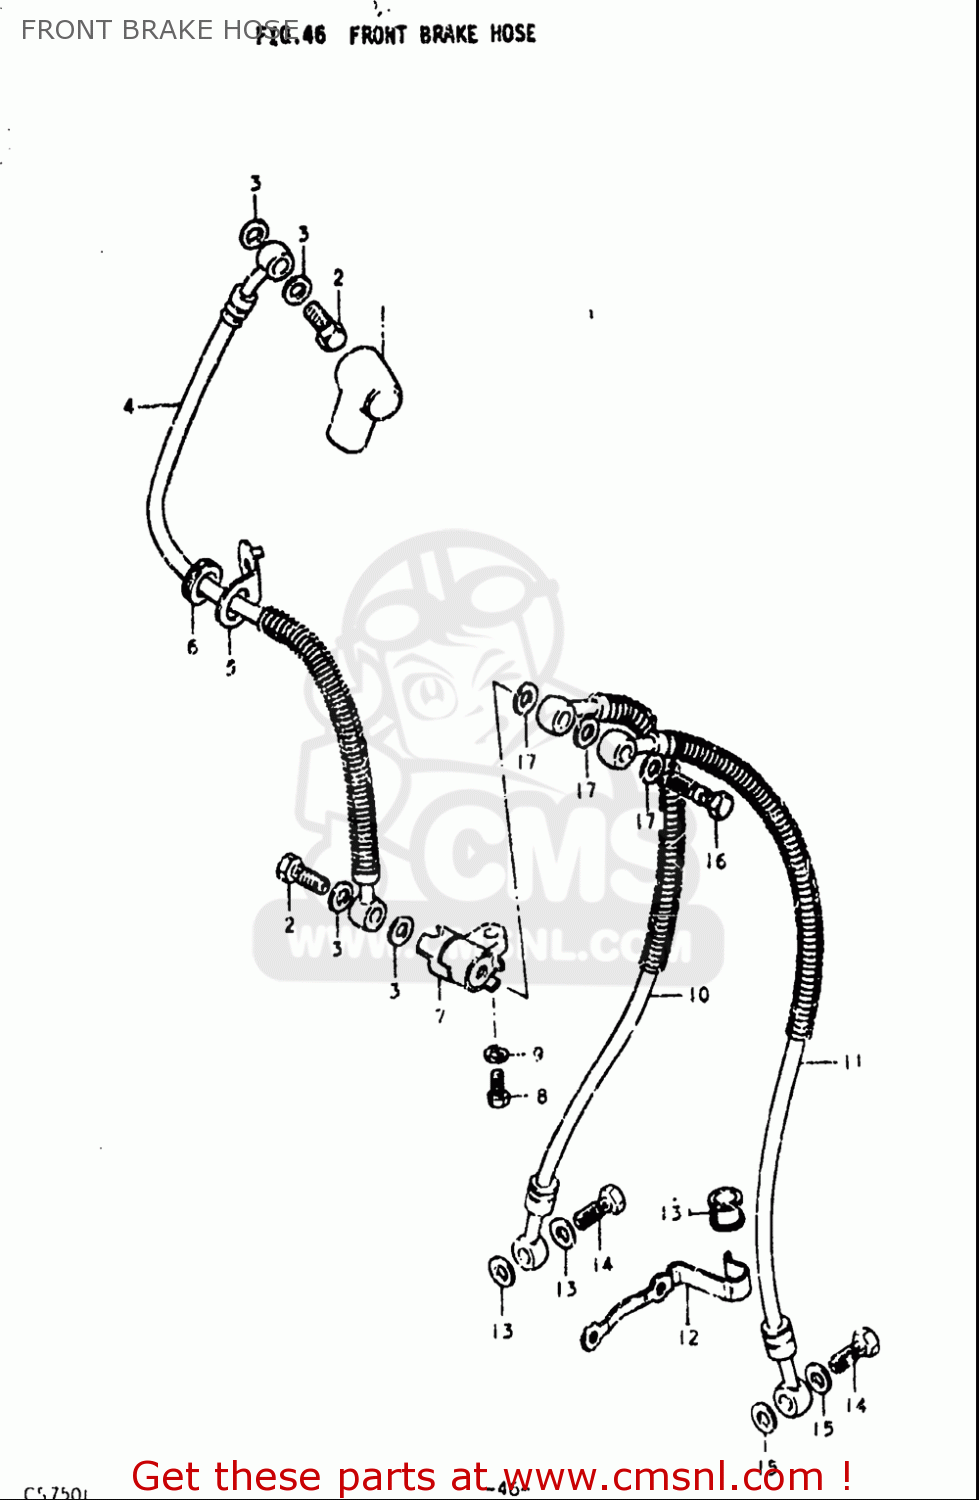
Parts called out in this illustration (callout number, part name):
1	BOOT,MASTER CYLINDER
2	BOLT UNION
3	WASHER(10X15X1.5)
4	HOSE,FRONT BRAKE NO.1
5	GUIDE,BRAKE HOSE
6	GROMMET
7	JOINT,BRAKE HOSE
8	BOLT
9	WASHER,LOCK
10	HOSE,FR BRAKE NO.2,L
12	GUIDE,BRAKE HOSE NO.2
13	BUSH,BRAKE HOSE GUIDE,NO.2
14	BOLT UNION
15	WASHER(10X15X1.5)
16	BOLT UNION
17	WASHER(10X15X1.5)
